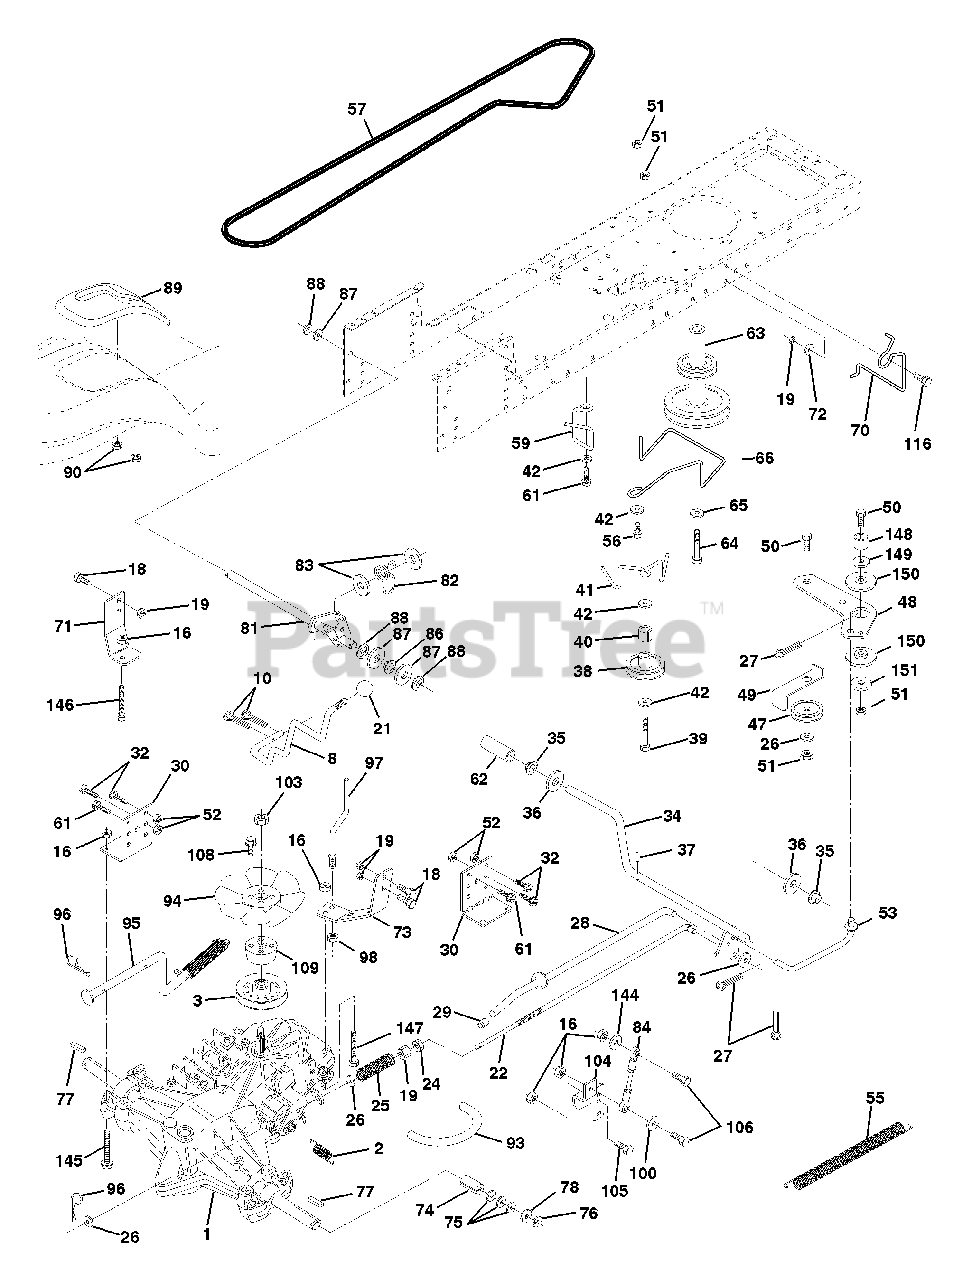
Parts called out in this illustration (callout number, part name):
1	Transaxle
2	Spring, Return, Brake
3	Pulley, Transaxle
8	Rod Shift Fender STLT
10	Pin Cotter 1/8 x 1 CAD
16	Nut Lock Hex W/Ins. 5/16-18 Unc P
18	Bolt Fin Hex 3/8-16 Unc x 1 Gr. 5
19	Nut Lock Hex W/Wsh 3/8-16 Unc
20	Bolt Hex 7/16-20 x 4 Gr 5
21	Knob, Duckhead 1/2-13
22	Rod, Brake Hydro
24	Nut
25	Spring, Brake Rod
26	Washer
27	Pin Cotter 1/8 x 3/4 CAD.
28	Rod, Parking Brake
29	Cap, Parking Brake
30	Bracket, Transaxle
32	Bolt Hex Hd 5/16-18 Unc x 3/4
34	Shaft, Foot Pedal
35	Bearing, Nylon
37	Pin, Roll
38	Pulley, Idler, Flat
40	Spacer, Split
41	Keeper, Belt Idler
42	Washer 13/32 x 13/16 x 12 Gauge
47	Pulley, Idler, V-Groove
48	Bellcrank Clutch Grnd Prv STL
49	Retainer, Belt
50	Bolt
52	Nut Crownlock 5/16-18
53	Link, Clutch
55	Spring, Return, Clutch
56	Bolt Fin Hex 3/8-16 UNC x 1-1/4
57	V-Belt, Ground Drive
59	Keeper, Center Span
61	Screw Thdrol. 3/8-16 x 3/4 Ty. TT
62	Cover, Pedal
63	Pulley, Engine
65	Washer
66	Keeper Belt Engine Hydro
70	Guide Belt Mower Drive RH
71	Strap Torque Lh Hydro
72	Washer 13/32 x 1-1/4 x 12 Ga.
73	Strap Torque Rh Hydro
74	Spacer, Split
75	Washer 25/32 x 1-1/4 x 16 Gauge
77	Key, Square
78	Washer 25/32 x 1-5/8 x 16 Gauge
81	Shaft Asm. Cross Hydro
82	Spring Torsion T/A
83	Washer 17/32 x 3/4 x 16 Ga.
84	Rod, Tie Hydro
87	Washer 21/32 x 1-1/4 x 16 Ga.
88	Ring Klip #5304-62
89	Console, Shift
90	Nut, Self-Thd Wsh-hd 1/4 Zinc
93	Line Fuel Hydro 4"
94	Fan, Hydro 7"
95	Control Asm Bypass Hydro
96	Retainer Spring 1" Zinc/Cad
97	Keeper Belt Rh Hydro
98	Nut Keps Hex 3/8-16 Unc
100	Washer 11/32 x 3/4 x 16 Ga.
103	Nut Nylon Insert 1/2-20 Unf.
104	Arm, Control Hydro
105	Screw Cap Hex 5/16 x 18 x 1
106	Bolt Fin Hex 5/16-18 Unc x 1-1/4
108	Screw Hex Wh Hd #10-24 x
109	Adaptor Fan Hydro LT Hyd Alum
116	Bolt Rdhd Sq. Neck 3/8-16 x 1.25
145	Bolt Hex Flghd 5/16-18 x Gr. 5
146	Bolt Hex Flghd 5/16-18 x 2-1/4
147	Bolt hex Flghd 5/16-18 x 1-1/2
149	Spacer Retainer PM Mower
150	Bushing Nylon Collered
151	Washer 13/32 x 2 x 10 Ga.
